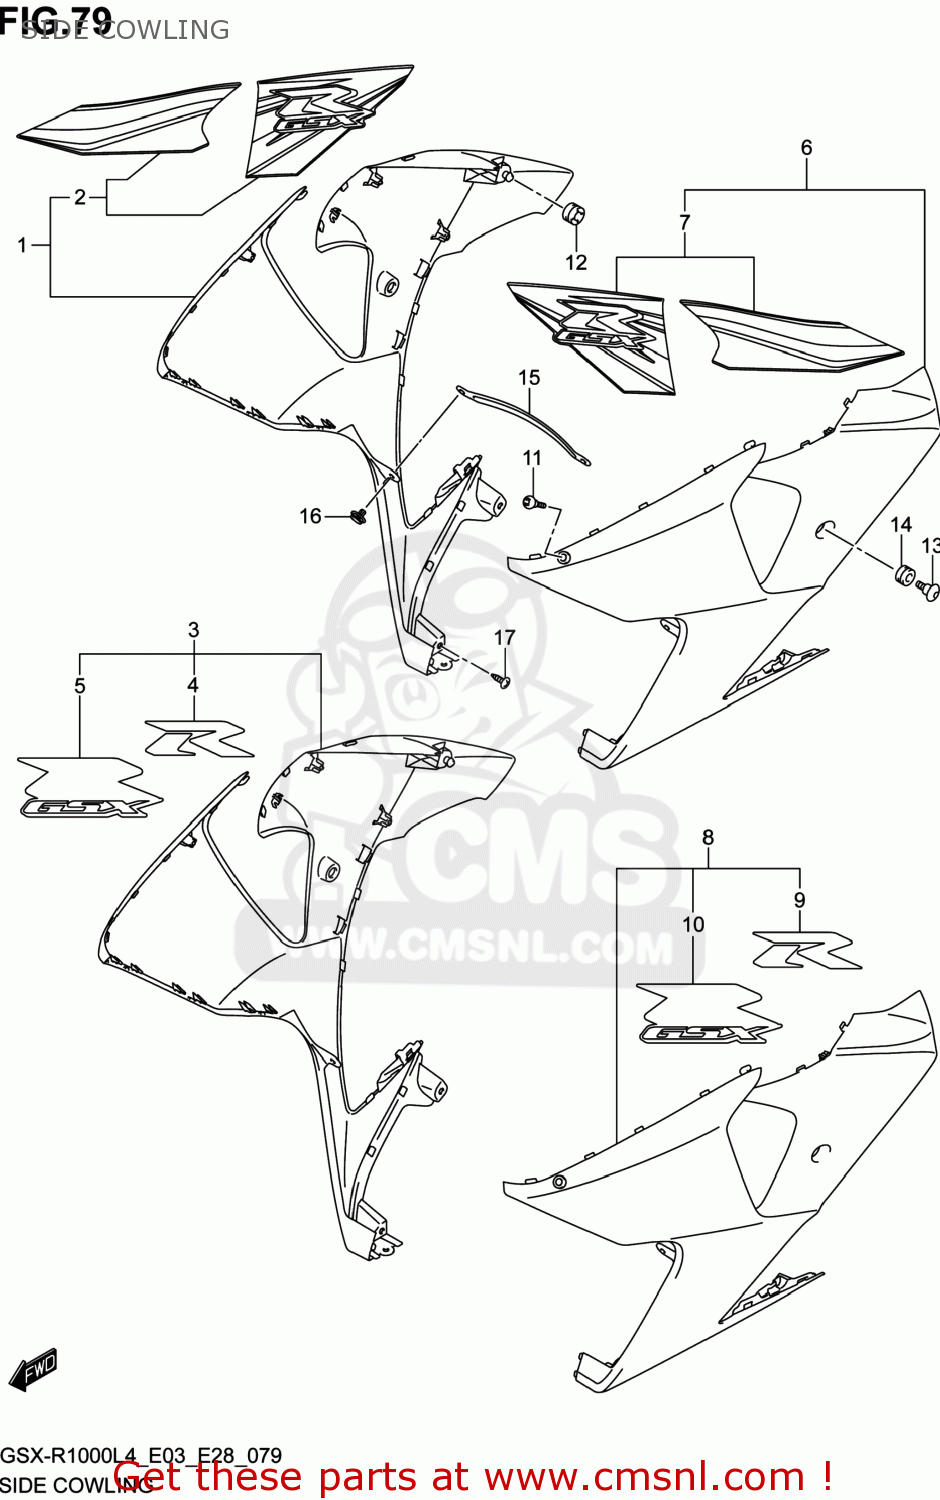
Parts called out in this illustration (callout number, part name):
1	COWLING,SIDE,R(BLACK)
2	TAPE SET,SIDE COWLING,R
3	COWLING,SIDE,R(BLACK)
4	EMBLEM,R
5	EMBLEM,GSXR,R
6	COWLING,SIDE,L(BLACK)
7	TAPE SET,SIDE COWLING,L
8	COWLING,SIDE,L(BLACK)
9	EMBLEM,R
10	EMBLEM,GSXR,L
11	SCREW(5X16)
12	CUSHION
13	BOLT(6X20)
14	CUSHION
15	BRACKET,UNDER COWLING CTR
16	CLIP
17	SCREW
